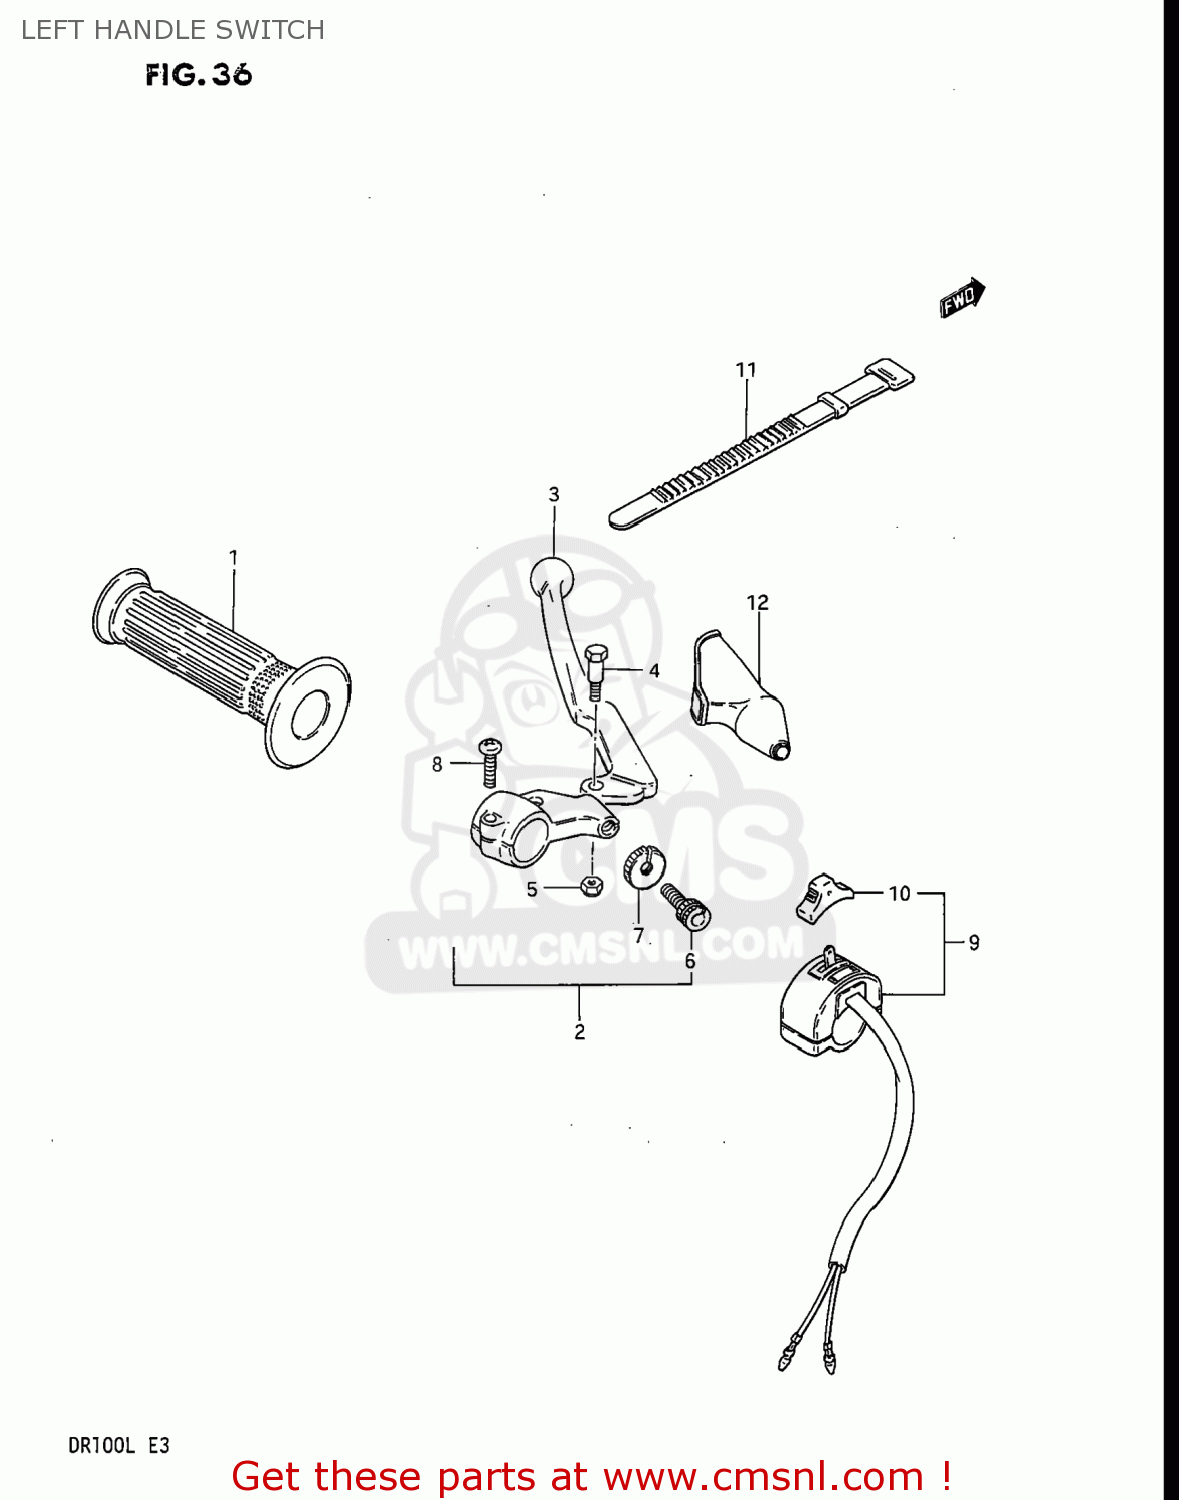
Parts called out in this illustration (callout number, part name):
1	GRIP,L
2	LEVER ASSY,CLUTCH
3	LEVER,CLUTCH
4	BOLT,LEVER
5	NUT 6MM
6	ADJUSTER,CABLE
7	NUT,CABLE ADJUSTER
8	SCREW
9	SWITCH ASSY,LIGHTING
10	KNOB,LIGHTING & DIMMER
11	CLAMP(L:120)
12	COVER,CLUTCH LEVER
